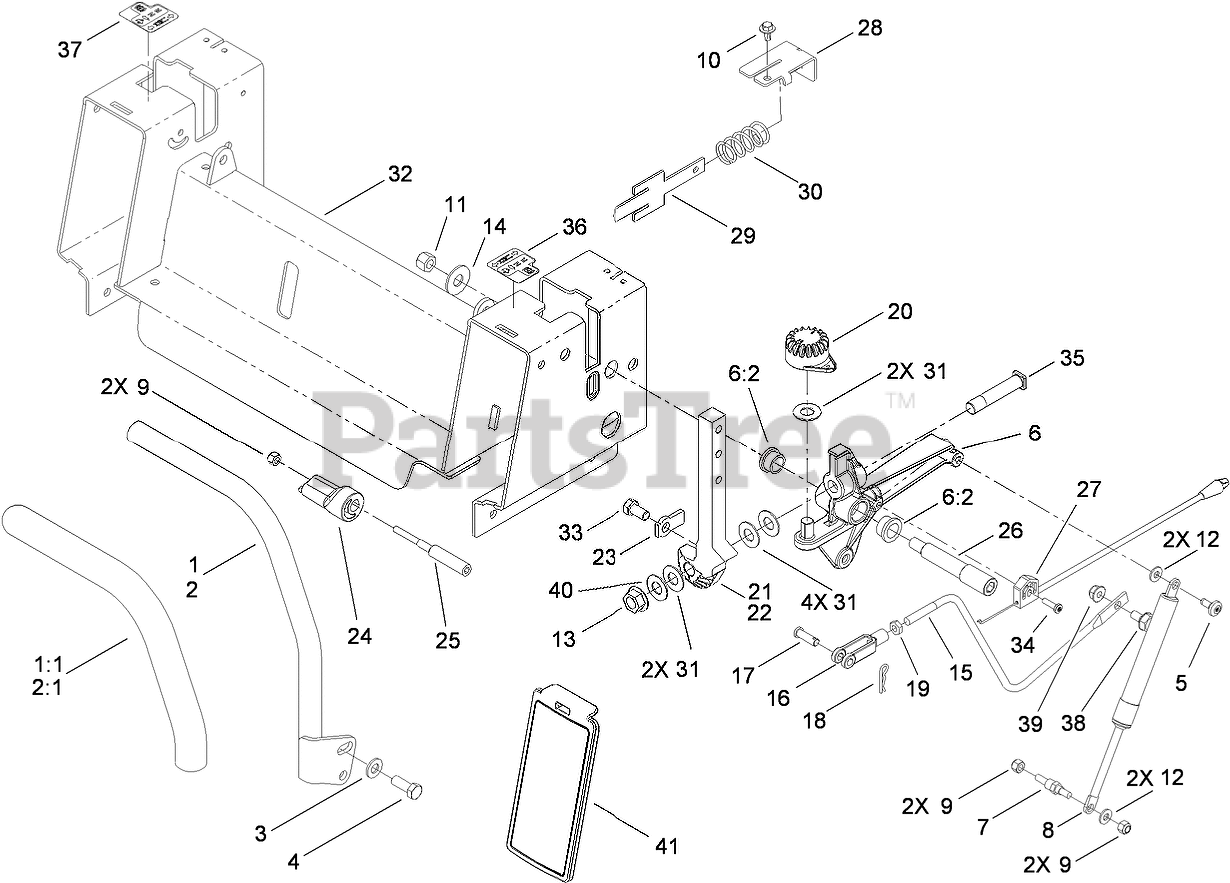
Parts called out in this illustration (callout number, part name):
1	RH CONTROL HANDLE ASM
3	WASHER-FLAT
4	SCREW-HH
5	SCREW-SHOULDER
6	ACTIVATOR ARM ASM
6:2	BUSHING
7	STUD-DAMPER
8	Damper-Control, Motion
9	NUT-LOCK, NI
10	SCREW-HHFTF
11	NUT-LOCK, NI
12	WASHER-FLAT
13	NUT-HF
14	WASHER-FLAT
15	LINK-HYDRO
16	YOKE-ADJUSTABLE
17	PIN-CLEVIS
18	PIN-COTTER
19	NUT-JAM
20	GEAR-CONTROL
21	ARM-ACTUATOR, LH
23	TAB-STOP
24	ECCENTRIC
25	SCREW-ECCENTRIC
26	BOLT-SHOULDER
27	CABLE-BRAKE, PARKING
28	BRACKET-RETURN
29	PLATE-RETURN
30	SPRING-COMPRESSION
31	WASHER-PIVOT
32	SEAT PIVOT/CONTROL ASM
33	SCREW-HH
34	SCREW-TORX
35	BOLT-SHOULDER
36	DECAL-CONTROL LEVER, LH
37	DECAL-CONTROL LEVER, RH
38	BOLT-SHOULDER
39	NUT-HF, NI
40	WASHER-TEFLON
41	COVER-CONTROL
